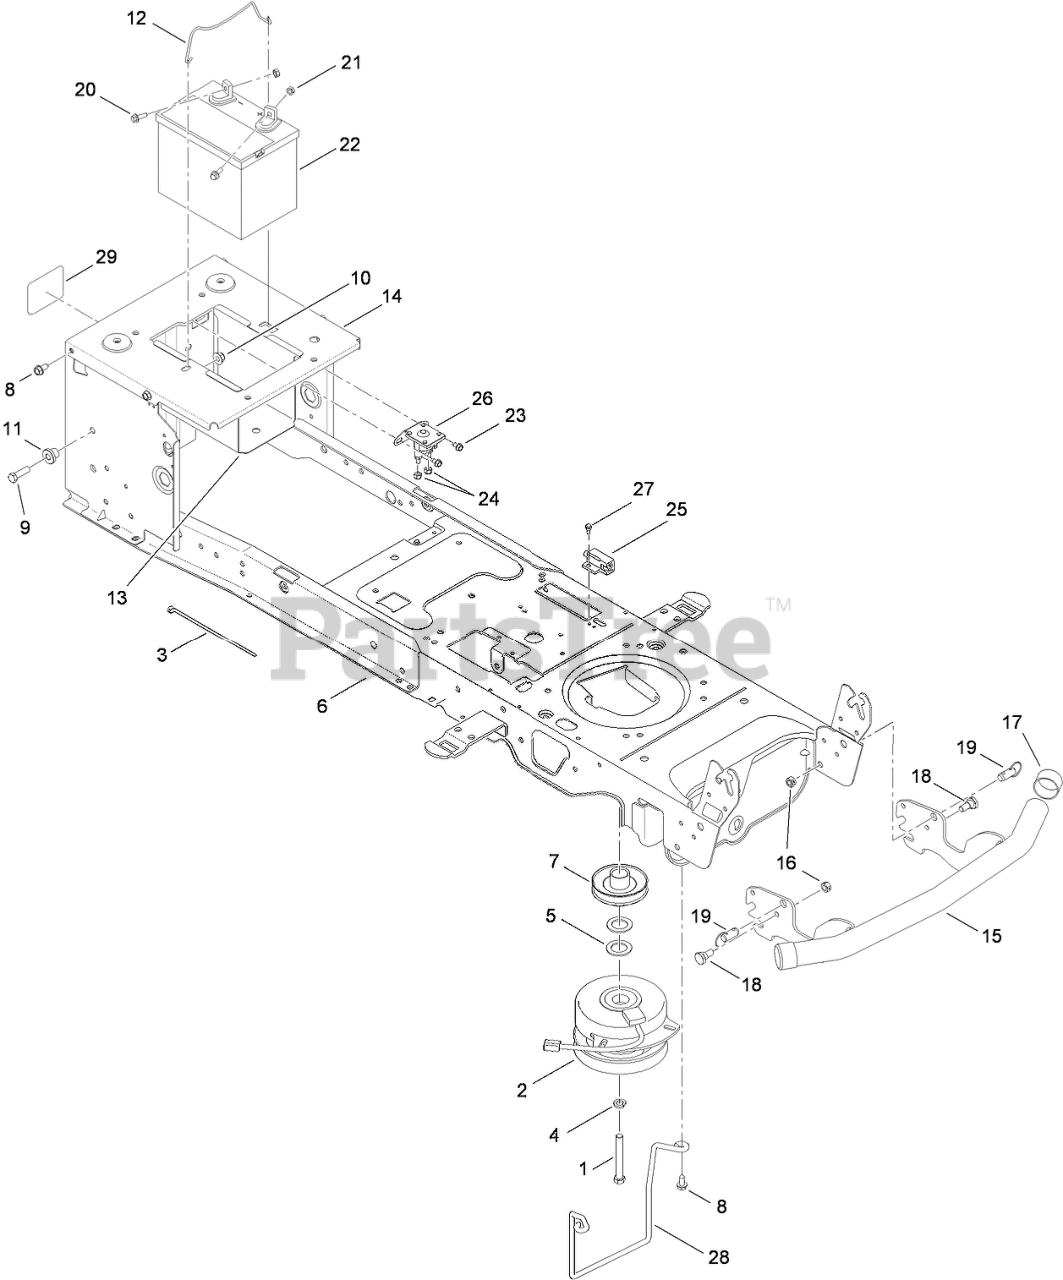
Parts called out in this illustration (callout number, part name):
1	SCREW-HH
2	CLUTCH-ELECTRIC
3	TIE-CABLE
4	WASHER-LOCK
5	WASHER-FLAT
6	LOWER FRAME ASM
7	PULLEY-ENGINE
8	SCREW-TAP
9	SCREW-HH
10	NUT-LOCK, FLANGE
11	SPACER-SHOULDER
12	ROD-HOLDDOWN, BATTERY
13	TRAY-BATTERY
14	BRACKET-FRAME, SEAT
15	BUMPER-UNIVERSAL
16	NUT-LOCK
17	CAP-HUB
18	BOLT-SHOULDER
19	PIN-RELEASE, QUICK
21	NUT-SEMS
22	BATTERY-245, CCA (DRY FLAT TOP)
23	SCREW-TAP
24	NUT-LOCK, FLANGE
25	SWITCH-INTERLOCK, NO/NC
26	SOLENOID-12V, 2 POST 2 Tab
27	BOLT-SHOULDER
28	ROD-KEEPER, BELT
29	DECAL-RELEASE, HYDRO
